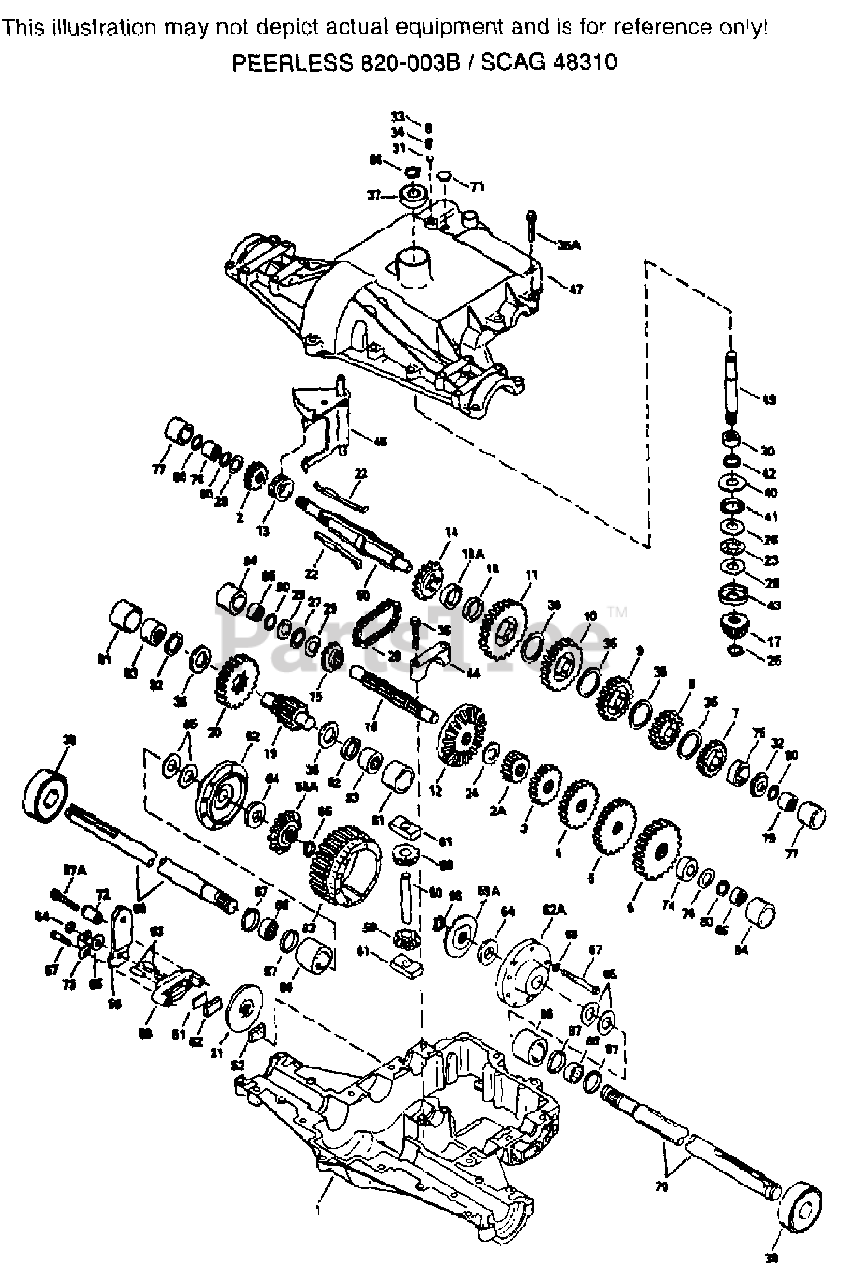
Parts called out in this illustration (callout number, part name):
1	CASE, TRANSAXLE
2	GEAR, SPUR(15 TEETH)
3	GEAR, SPUR(15 TEETH)
4	GEAR, SPUR(20 TEETH)
5	GEAR, SPUR(25 TEETH)
6	GEAR, SPUR(28 TEETH)
7	GEAR, SPUR(22 TEETH)
8	GEAR, SPUR(25 TEETH)
9	GEAR, SPUR(30 TEETH)
10	GEAR, SPUR(35 TEETH)
12	GEAR, BEVEL(33 TEETH)
13	COLLAR, SHIFT
14	SPROCKET(18 TEETH)
15	SPROCKET(9 TEETH)
16	SHAFT, COUNTER
17	BEVEL PINION, INPUT
18	SPACER, NEUTRAL
18A	SPACER, NEUTRAL
19	SHAFT, OUTPUT(9 TEETH)
20	GEAR, OUTPUT(35 TEETH)
21	DISC, BRAKE
23	BEARING, THRUST
24	WASHER, THRUST
25	RING, RETAINING
26	WASHER, THRUST
27	BEARING, THRUST
28	CHAIN, ROLLER(NO. 41 CHAIN, 24 LINKS)
29	WASHER, THRUST
30	BEARING, NEEDLE
31	BALL, STEEL
32	WASHER, THRUST
33	SCREW, SET, 3/8-16 X 3/8"
34	SPRING
35A	SCREW, HEX HEAD. THRD. FRM, 5/16-18 X 1-1/4"
36	WASHER, THRUST
37	BEARING, BALL
38	WASHER, THRUST
39	BEARING, BALL
40	WASHER, FLAT
41	"O" RING
42	SEAL, OIL
43	WASHER, CUPPED
47	COVER, TRANSAXLE
48	ROD & FORK ASSEMBLY, SHIFT
49	SHAFT, INPUT
50	SHAFT BRAKE
51	PLATE, BRAKE PAD
52	PAD, BRAKE
53	PIN, DOWEL
54	LOCKNUT, 5/16-24
55	WASHER, FLAT
56	LEVER, BRAKE
57	SCREW, HEX HEAD, THRD. FRM, 1/4-20 X 1-1/4"
57A	SCREW, HEX HEAD, THRD. FRM, 1/4-20 X 2-1/4"
58	HOLDER, BRAKE PAD
59	PINION, DIFFERENTIAL BEVEL
59A	GEAR, BEVEL
61	BLOCK, DRIVE
62	CARRIER, DIFFERENTIAL(THREADED HOLES)
62A	CARRIER, DIFFERENTIAL
63	GEAR, RING(31 TEETH)
64	WASHER
65	WASHER, THRUST
66	RING, SNAP
67	SCREW, HEX HD., 1/4-20 X 2-1/4"
69	AXLE(12-1/4" LONG)
70	AXLE(24-1/4" LONG)
71	PLUG, HEX HD., 9/16-18
72	SPACER
73	BRACKET, BRAKE LEVER
74	SPACER
75	SPACER
76	WASHER
77	SLEEVE(STEPPED)
78	BEARING, NEEDLE
79	BEARING, NEEDLE(CAPPED)
80	"O" RING
81	SLEEVE(STEPPED)
82	RING, SQUARE CUT
83	BEARING, NEEDLE(CAPPED)
84	SLEEVE(STEPPED)
85	BEARING, NEEDLE(CAPPED)
86	SLEEVE(STEPPED)
87	RING, SQUARE CUT
88	BEARING, NEEDLE
